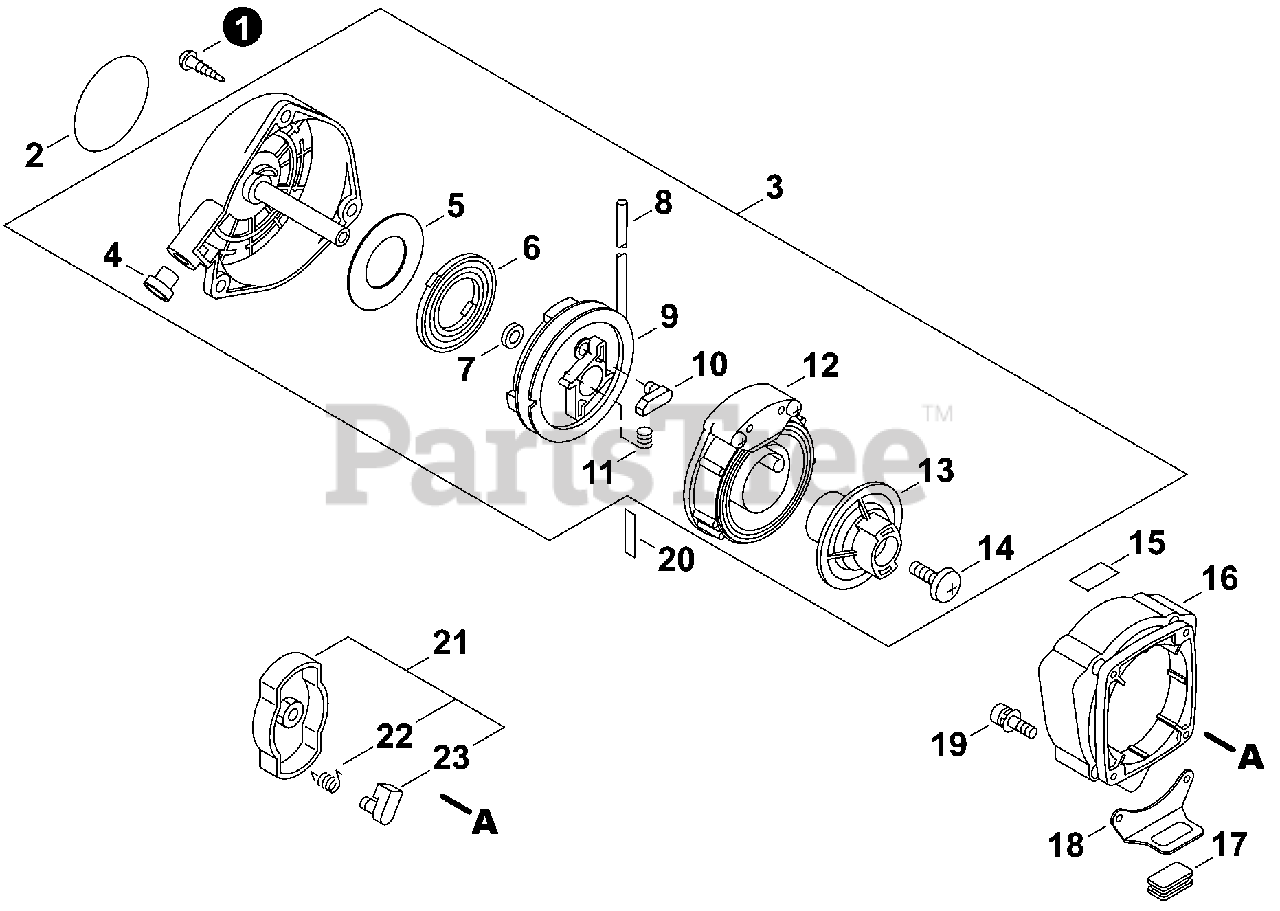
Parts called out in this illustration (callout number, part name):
1	SCREW, TAPPING 5x20
2	LABEL - ECHO
3	STARTER ASSY, RECOIL
4	GUIDE, ROPE
5	PLATE, STARTER
6	SPRING, RECOIL
7	COLLAR 8
8	ROPE, STARTER 3x1300
9	REEL, ROPE
11	SPRING, COMPRESSION
12	SPRING ASSY, POWER
13	PULLEY, STARTER
14	SCREW 5
15	LABEL - CAUTION - HOT
16	COVER, RECOIL STARTER
18	PLATE, ANGLE
19	BOLT 4x14
20	LABEL - CAUTION
21	PAWL ASSY, STARTER
22	SPRING, RETURN
23	PAWL, STARTER - BLACK
